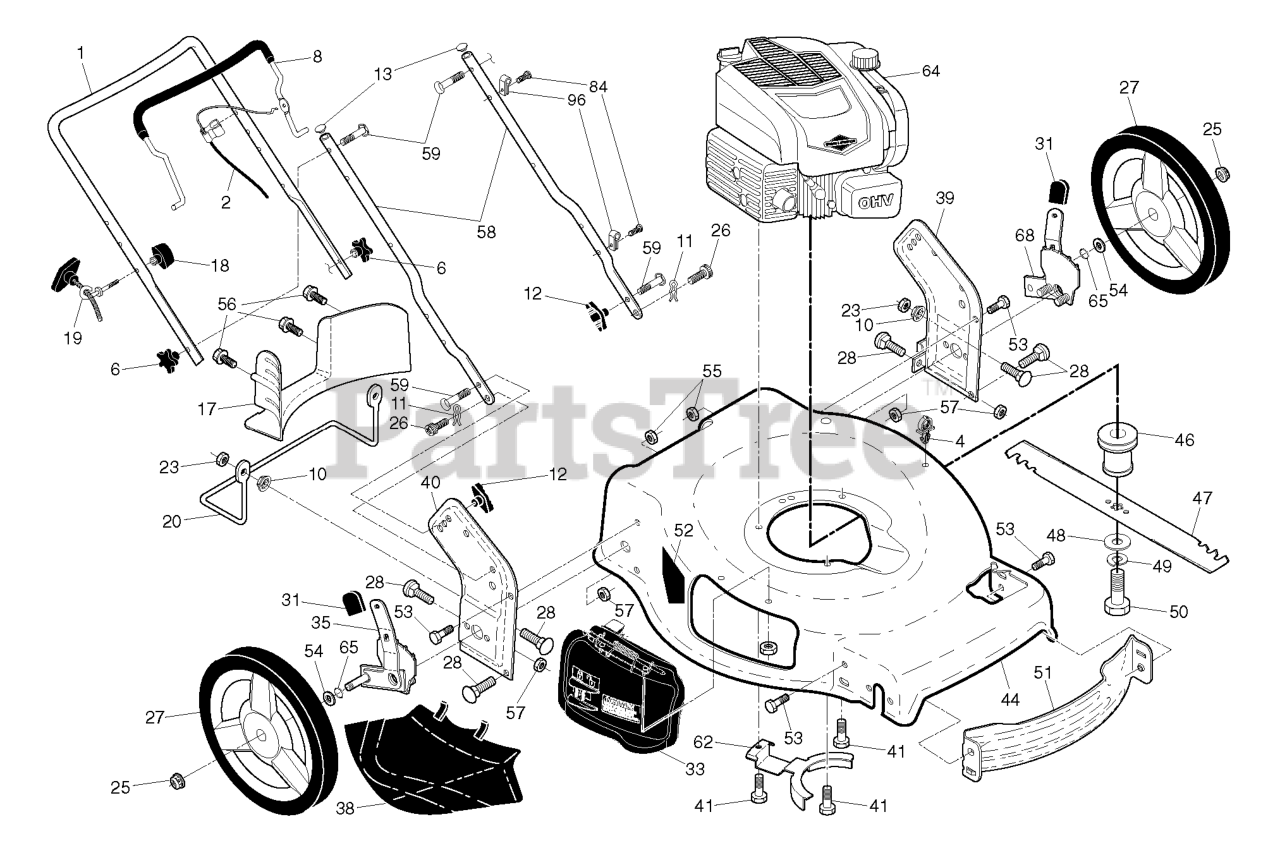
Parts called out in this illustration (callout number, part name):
1	HANDLE.UP.CURV.PUSH.498
2	CABLE.MZR.FGD.PLUS
6	KNOB.HANDLE.PLASTIC.STAR.BLACK
8	BAIL.OM.ERGO.BENT.MZR.ORAN.668
10	WASHER 5/16"
11	COTTER.HAIRPIN.DOOR/HANDLE.PIV
12	KNOB, DEFLECTOR
13	PLUG.PLASTIC.7/8".14-20.GAUGE
17	BAFFLE.22PLUS.FGD.REAR.
18	T-KNOB.NEW ROPE GUIDE
19	GUIDE.ROPE.BLK.ZINC.CHROM
20	FOOTGUARD.REAR.22PLUS.BLK
23	LOCKNUT-FLANGE 5/16-18
25	NUT.HEX.FLANGE.3/8-16.LOCKNUT
26	SCREW,DOOR/HANDLE.PIVOT
27	WHEEL.12X1.75.CF H3SPK.RAD3.BB
28	BOLT.CARRIAGE.LN.5/16-18X.5/8
31	SELECTOR KNOB
33	DOOR ASSY KIT.MULCH DOOR.CE 22
35	ADJUSTER.ASM.9POS.HW.R/R
38	DEFLECTOR.CLIPPING.22.BLACK
39	BRACKET.ASM.HANDLE.LT.22+.GREY
40	BRACKET.ASM.HANDLE.RT.22+.GREY
41	BOLT 3/8-16X1-1/8
44	KIT.HSG.22+FGD.SIDE.668.CE
46	ADAPTER.BLADE.25M.22+FGD.2PIN
47	BLADE.22+4N1.2PIN.5STAR.(P07)
48	WASHER,HARDEN
49	LOCKWASHER
50	SCREW, HEX HD 3/8-24 X 1-3/8
51	BAFFLE.FRONT.22.PLUS
52	DECAL.INTERNATIONL.CUTFINGER
53	BOLT.5/16HEX.WHS.HD
54	WASHER.FLAT.1/2
55	NUT.HEX.FLANGE.1/4
56	SCREW.HX.13X.750
57	NUT.FLANGE.5/16
58	HANDLE.LOWER.22+.BT.GRAY
59	BOLT, HANDLE 5/16-18X1.75
62	BRACKET.ENG/BELTKEEPER
65	O-RING..070X.487.NEOPRENE
68	ADJUSTER.ASM.9POS.HW.R/L
84	FASTENER.PUSH.O.250X0.783
96	CLIP.CABLE.BLK
